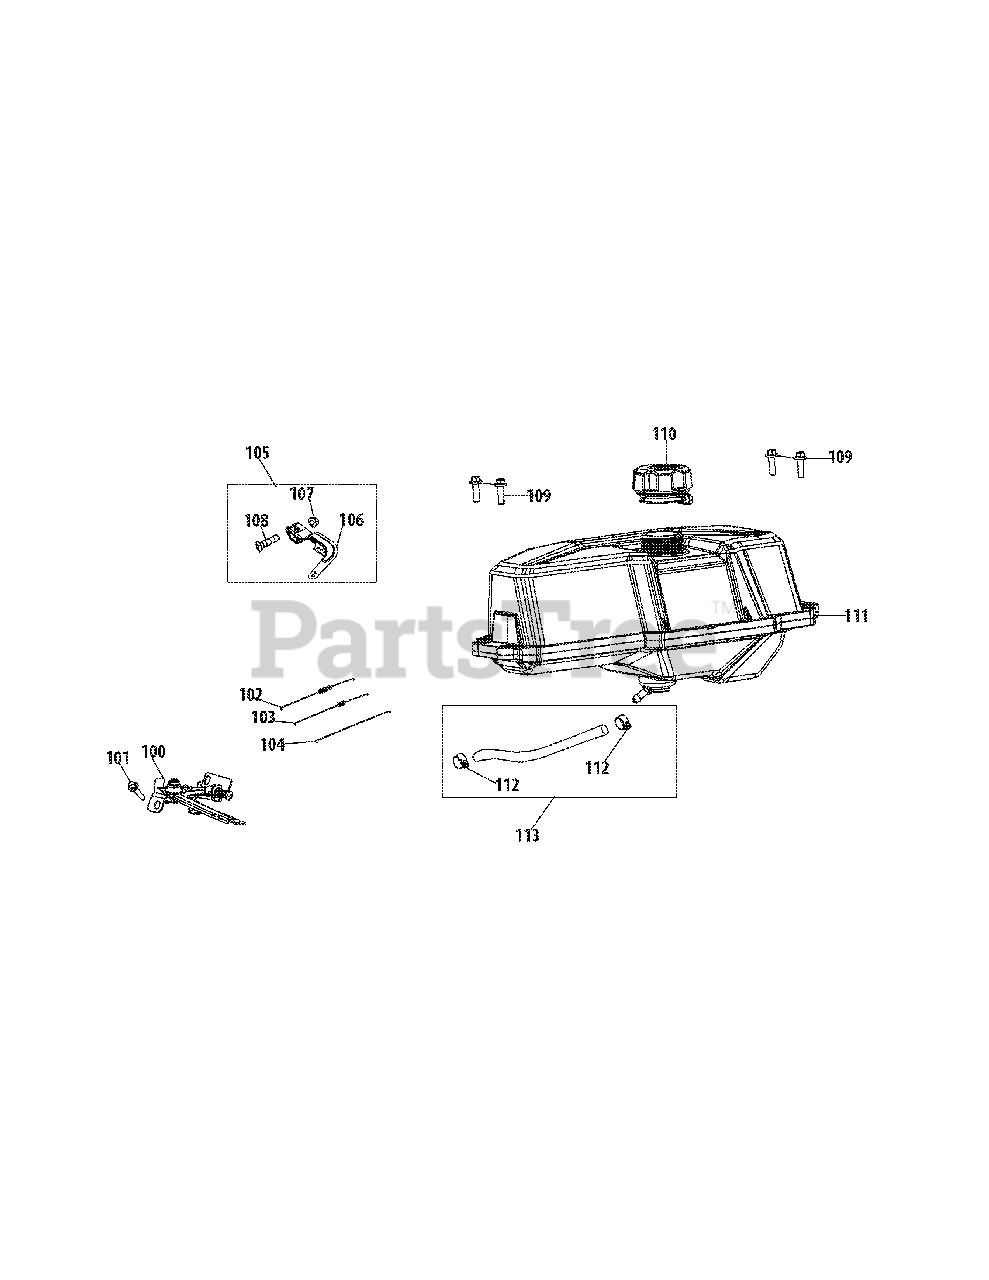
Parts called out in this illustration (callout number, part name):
100	Governor Gear Bracket Assembly
101	Bolt, M6×12
102	Governor Spring
103	Idle Spring
104	Throttle Linkage
105	Governor Lever
106	Governor Lever
107	Nut, M6
109	Bolt, M6×22
110	Fuel Cap
111	Fuel Tank
112	Clamp
113	Fuel Hose, 6.3×12.5×133
